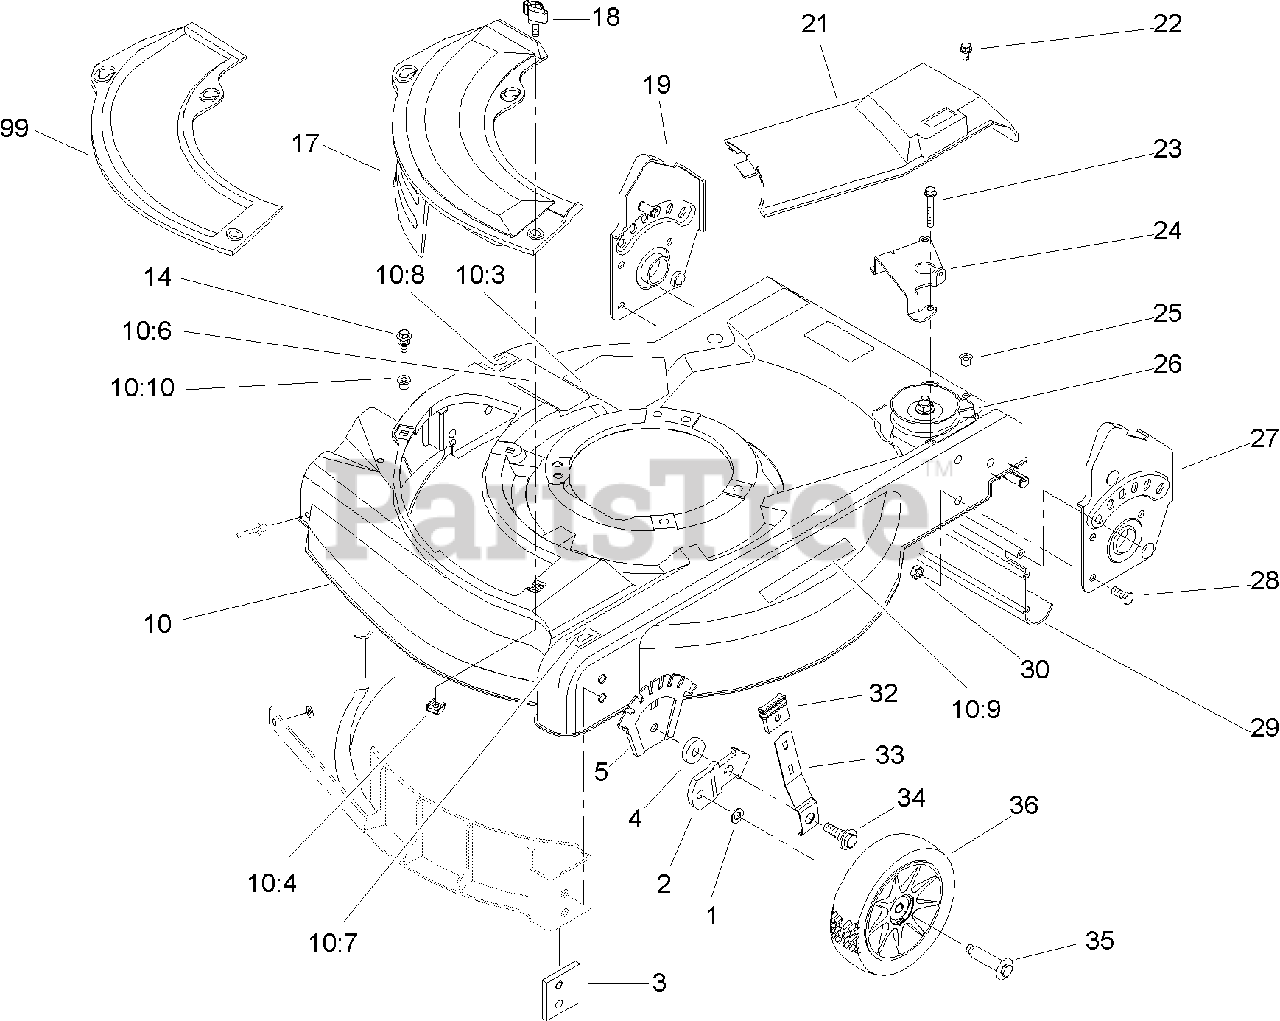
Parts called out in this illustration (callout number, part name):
2	BRACKET-HEIGHT ADJUSTMENT, WHEEL
3	PLATE-BAFFLE
4	WASHER-WHEEL
5	PLATE-HEIGHT, ADJUSTMENT
10:3	DECAL-DANGER
10:4	NUT-CAGE
10:6	DECAL-WARNING
10:7	DECAL-HOC, LH
10:8	DECAL-HOC, RH
10:9	DECAL-WARNING
10:10	NUT-CLIP
14	SCREW-SEMS
17	PLATE-MULCH
19	RH BRACKET ASM
21	COVER-DRIVE
22	SCREW-THREAD CUT
23	SCREW-HWHTF
24	Guide-Transmission
25	NUT-CLIP
26	GEAR CASE ASM
27	LH BRACKET ASM
28	SCREW-HH
29	SHIELD-TRAILING
30	NUT-LOCK, NI
32	KNOB-LEVER, HEIGHT ADJUSTMENT
33	ARM-FRONT SPRING
34	BOLT-SHOULDER
35	BOLT-SHOULDER
36	WHEEL AND TIRE ASM
99	PLATE-OPENING, CHUTE
